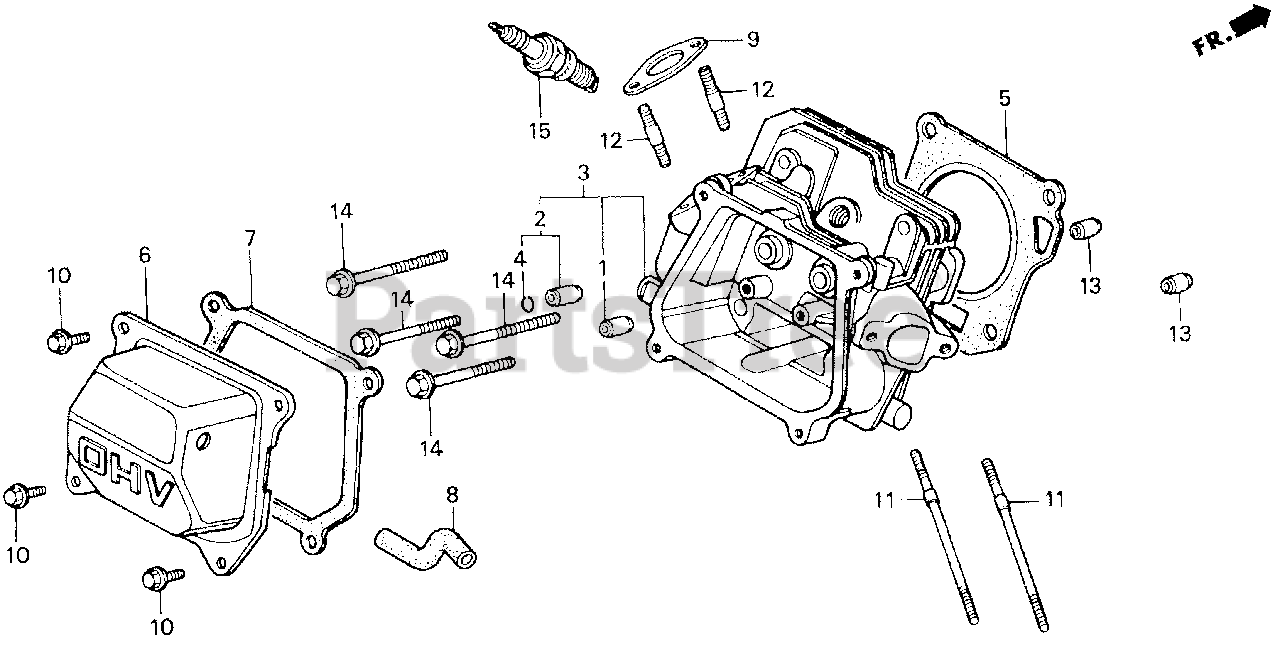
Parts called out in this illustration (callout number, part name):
1	GUIDE, VALVE (OS)
2	GUIDE, EX. VALVE (OS)
3	CYLINDER HEAD
4	CLIP, VALVE GUIDE
5	GASKET, CYLINDER HEAD
6	COVER, HEAD
7	GASKET, CYLINDER HEAD COVER
8	TUBE, BREATHER
9	GASKET, MUFFLER
10	BOLT, FLANGE (6X12) (CT200)
11	BOLT, STUD (6X109)
12	BOLT, STUD (8X32)
13	PIN A, DOWEL (10X16)
14	BOLT, FLANGE (8X60)
15	SPARK PLUG (BPR6ES) (NGK)
15	SPARK PLUG (W20EPR-U) (DENSO)
